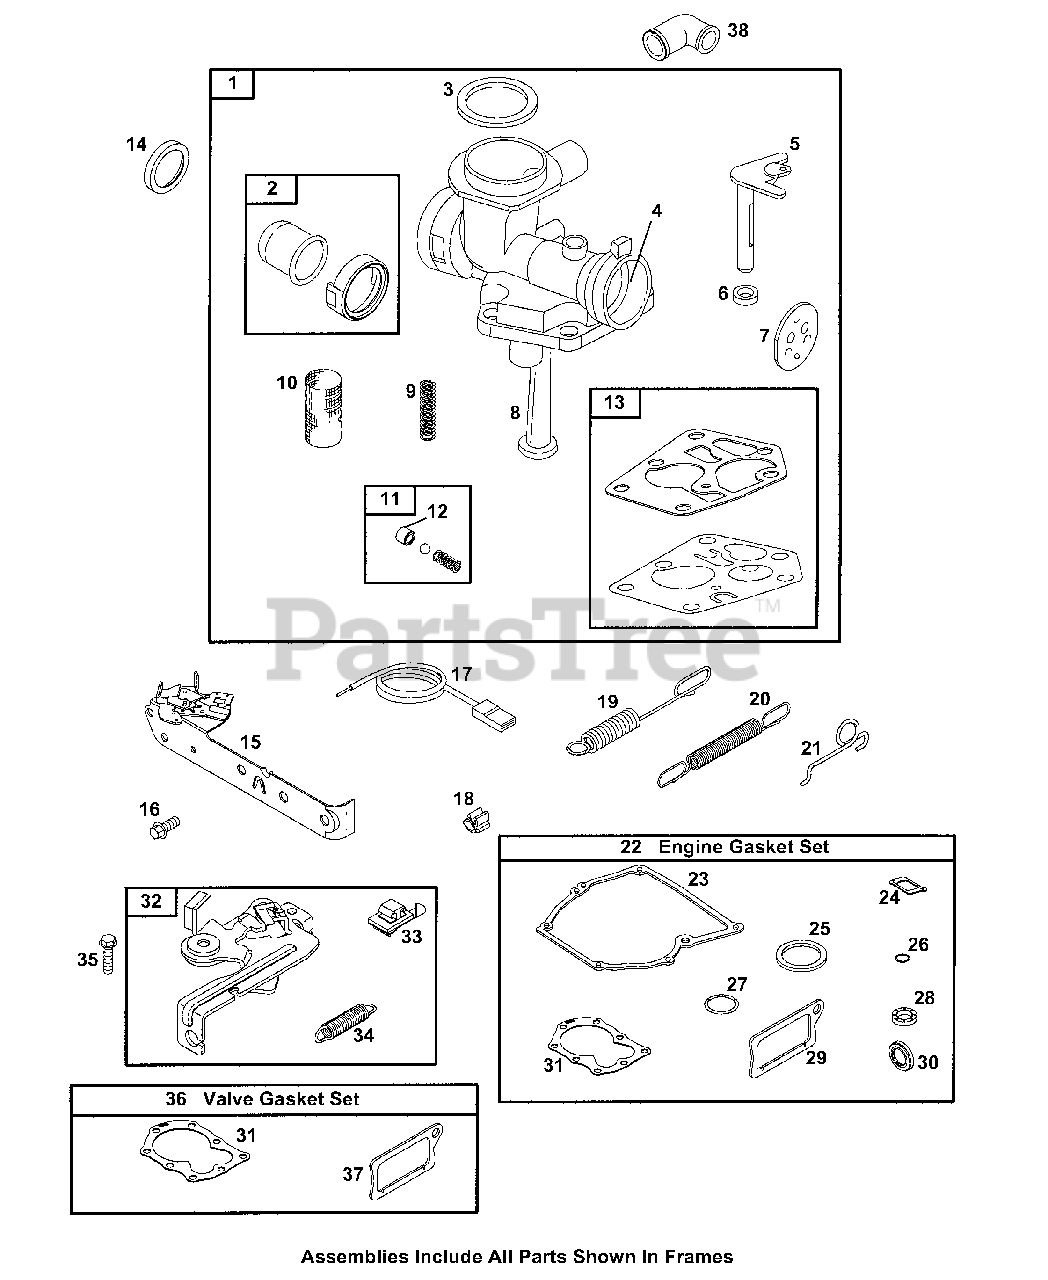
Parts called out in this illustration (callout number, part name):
1	Carburetor
2	Carburetor Primer
3	Air Cleaner Gasket
4	O-Ring Seal (Intake Manifold)
5	Throttle Shaft
6	Choke/Throttle Shaft Seal
7	Throttle Valve
8	Pick Up Tube
9	Choke Diaphragm Spring
10	Carburetor Screen
11	Check Valve Seat
12	Inlet Seat
13	Carburetor Pump Gasket
14	Trim Ring (Primer Bulb)
15	Control Bracket
16	Screw (Control Bracket)
19	Governor Spring
20	Governor Idle Spring
21	Air Vane Link
22	Engine Gasket Set
23	Crankcase Gasket (.015 Thick, Std)
24	Intake Gasket
25	Air Cleaner Gasket
26	Dipstick Tube Seal
27	Dipstick/Tube Seal
28	Oil Seal (PTO Side)
29	Breather Gasket
30	Oil Seal (Magneto Side)
31	Cylinder Head Gasket
33	Stop Switch
34	Brake Spring
35	Screw (Brake)
36	Valve Gasket Set
37	Breather Gasket
38	Grommet
